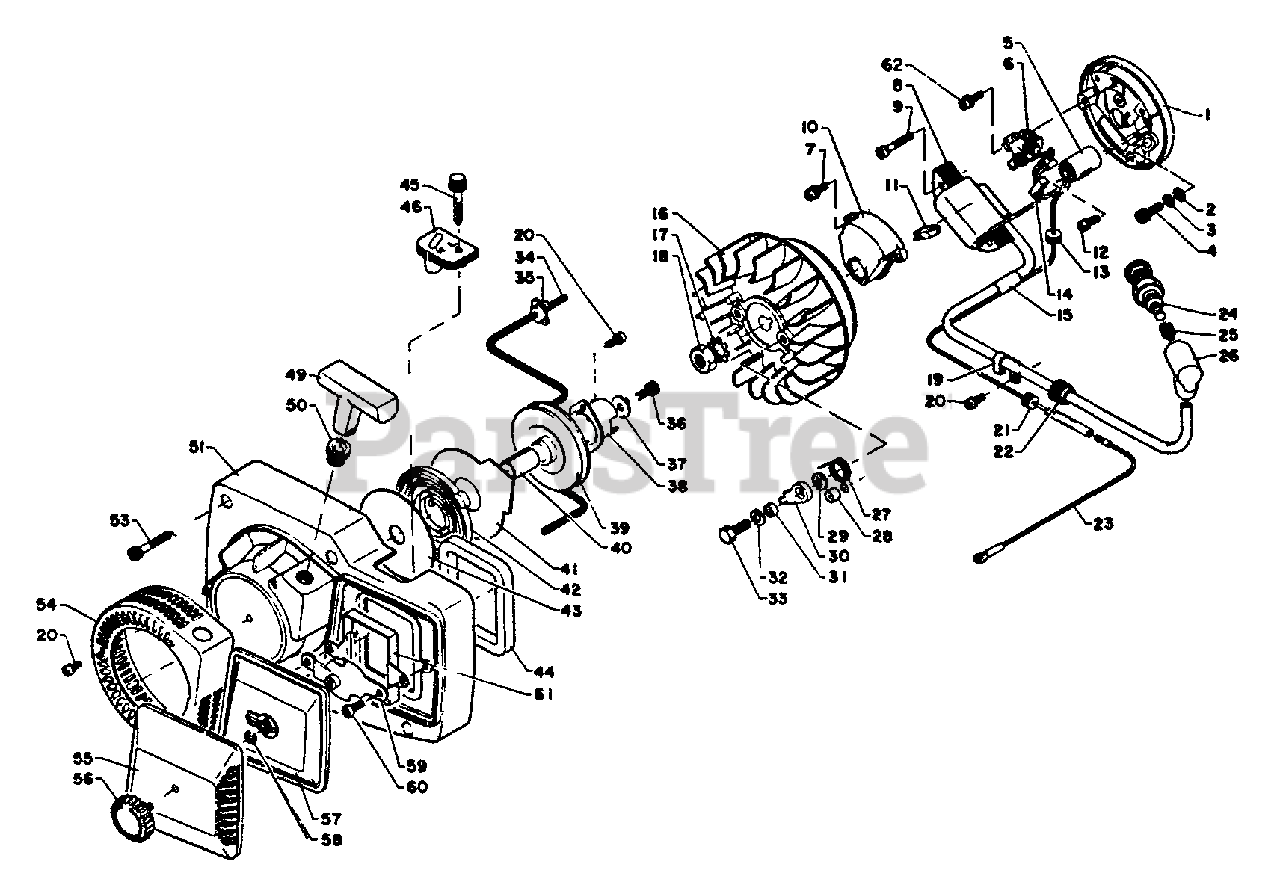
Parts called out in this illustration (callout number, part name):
1	PLATE, STATOR
2	WASHER - 5
3	LOCKWASHER - 5
4	SCREW - 5X15
5	CONDENSER
6	CONTACT POINT SET
7	SCREW - 4X14
8	COIL, IGNITION
9	SCREW - 4X25
10	COVER, BREAKER
11	PAD, OIL
12	SCREW - 4X10
13	GROMMET
14	GROMMET
16	FLYWHEEL
17	WASHER - 10
19	CLAMP
20	SCREW - 4X10
21	GROMMET
23	LEAD - GROUND
24	SPARK PLUG -- BPM-7A
25	TERMINAL, SPARK PLUG CAP
26	CAP, SPARK PLUG
27	SPRING, RETURN
30	PAWL, STARTER
32	WASHER - 6
33	BOLT - 6X16
34	ROPE, STARTER
35	RETAINER, ROPE
36	SCREW - 5X12
37	WASHER - 5
38	CATCHER, PAWL
39	REEL, ROPE
41	PLATE, STARTER
42	SPRING, REWIND
43	PLATE, STARTER
44	GASKET, CARBURETOR CASE
45	SCREW, IDLE ADJUST
46	GROMMET
49	GRIP, STARTER
50	GUIDE, ROPE
51	CASE, STARTER
53	SCREW - 5X30
54	FILTER, DEBRIS
55	COVER, AIR FILTER
56	THUMBSCREW
57	FILTER, AIR
58	RING, RETAINING - 4
59	PLATE, PREVENT
60	SCREW - 5X10
60	STARTER ASSY
60	STATOR ASSY
62	SCREW
